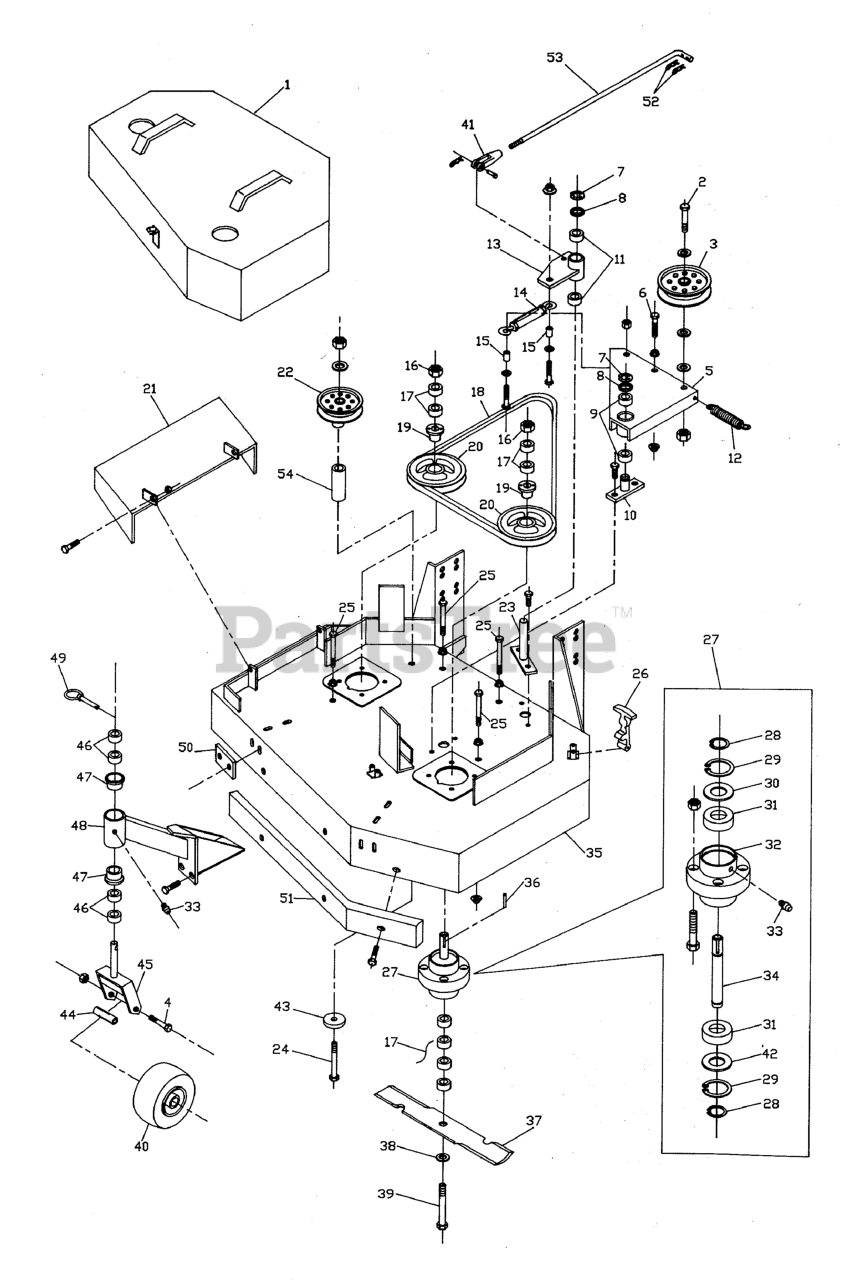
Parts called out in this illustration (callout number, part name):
1	36 " DECK GUARD
2	BOLT, 1/2-20 x 3
3	PULLEY, Backside Idler
4	BOLT, 1/2-13 x 5-1/2
5	CLUTCH PIVOT PLATE
6	BOLT, 3/8-16 X 1-3/4" GD5 CZ
7	C-CLIP
8	SHIM
9	BUSHING
10	IDLER MOUNT
11	BUSHING, Brass
12	SPRING, Extension
14	TURNBUCKLE ASSY
15	SLEEVE
16	NUT, 5/8-11 Hex
17	SPACER, .63 x 1.06 x .23
18	BELT, Deck Drive
19	BUSHING, Tapered Hub
20	PULLEY, Spindle
21	DISCHARGE CHUTE
22	IDLER PULLEY
23	Idler Pivot
24	BOLT, 1/2-13 x 4-3/4
25	BOLT, 3/8-16 x 5
26	RUBBER LATCH
27	SPINDLE ASSEMBLY, Complete
28	SNAP RING, External
29	SNAP RING, Internal
30	SPINDLE WASHER, Top
31	BEARING
32	SPINDLE HOUSING
33	GREASE FITTING
34	SPINDLE SHAFT
35	36" MOWER HOUSING
36	KEY, 1/4 SQ. X 2-1/2
37	MOWER BLADE, 18"
37	MOWER BLADE, 18" (High Lift)
38	WASHER, 5/8" USS
39	BOLT, 5/8-11 x 9-1/2
40	TIRE ASSM, Solid Rubber, 9 X 3.5
41	CLEVIS, 3/8-24, Plastic
42	SPINDLE WASHER, Bottom
44	AXLE, Caster Wheel
45	YOKE, Caster
46	SPACER, 1.02 x 1.56 x .50
47	BUSHING, Flange
48	Caster Support
49	PIN, Lynch
50	Caster Mount Spacer
52	HAIRPIN CLIP
53	Blade Engagement Rod
54	SPACER, .50 x 1.00 x 2.25
